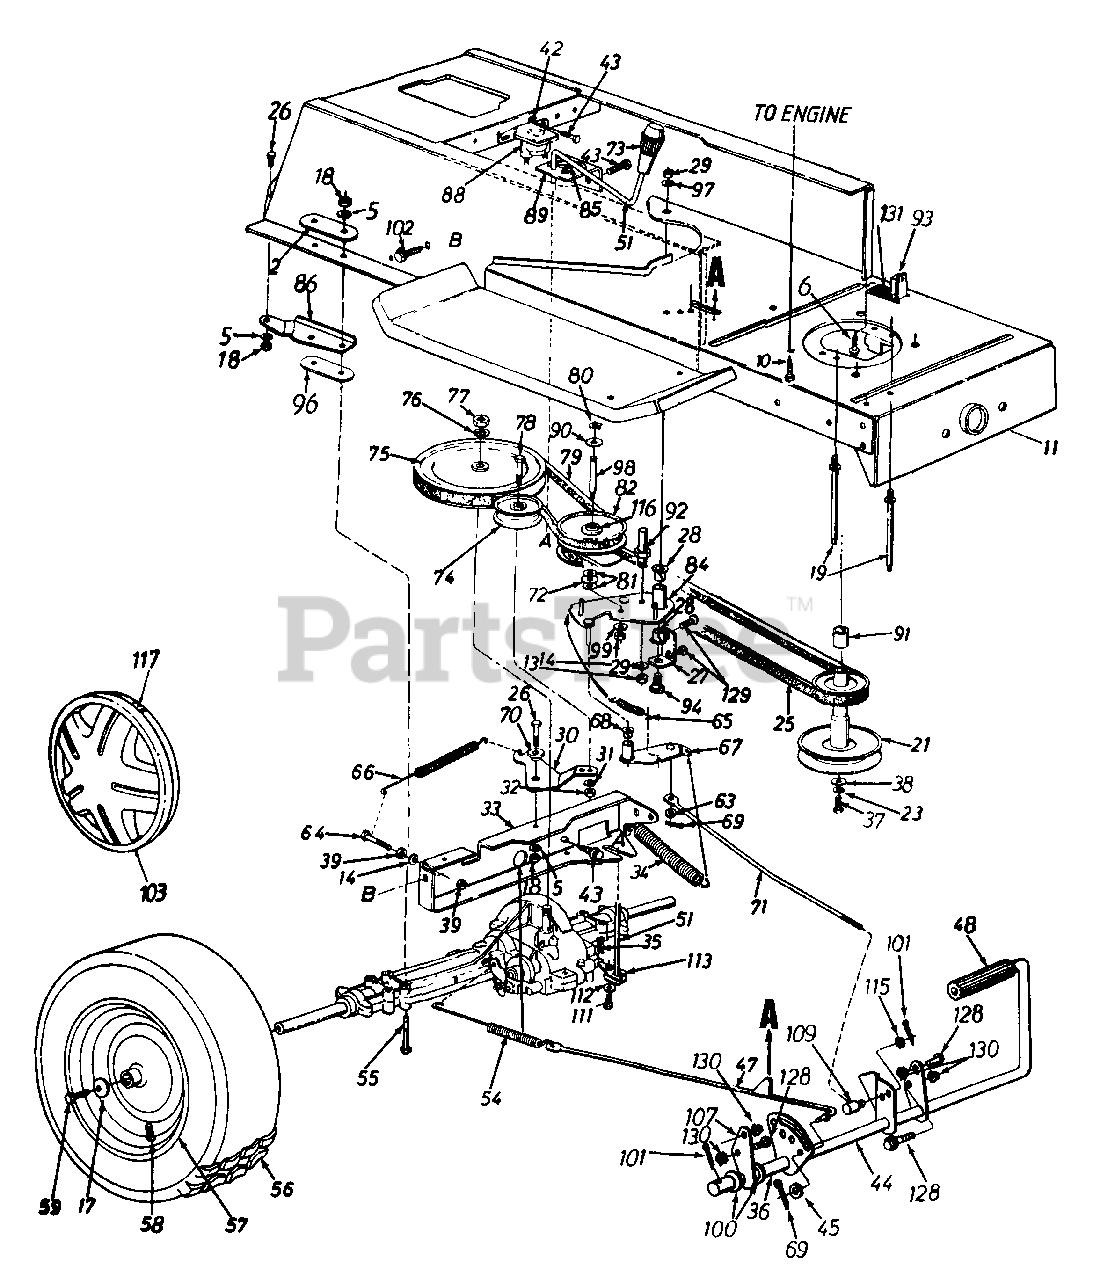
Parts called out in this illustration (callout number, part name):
5	L-Wash. 5/16" I.D.
6	Self-tap screw 1/4 x .50
10	Hex TT-Tap Scr. 3/8-16 x 1.5" Lg.
13	Hex Nut 1/4-20 Thd. (Gr. 5)
14	L-Wash. 1/4" I.D.
17	Bell-Wash. .345" I.D. x .88"
18	Hex Nut 5/16-18 Thd. (Gr. 5)
19	Belt Guard Stud 4.75" Lg.
21	Engine Pulley
23	L-Wash. 7/16" I.D.
25	Variable-Speed Belt
26	Hex Bolt 5/16-18 x .75" Lg.
27	Bearing Shaft Bracket Ass'y.
28	Flanged Nyliner Brg. 5/8" I.D. x .88" Lg.
29	Hex Nut 3/8-24 Thd.
31	L-Wash. 3/8" I.D.
32	Hex Nut 3/8-24 Thd.
35	Inter. Cotter Pin
36	Spacer .63" I.D.
37	Cap Scrw 7/16-20 x 1.25
38	Flat Washer .450
39	Hex Nut 1/4-28 Thd.
42	Ext. L-Wash. 1/4" I.D.
43	Hex Wash. Hd. S-Tap Scr. 1/4-20 x .50" Lg.
47	Brake Rod Ass'y.
48	Foot Pad
51	Shift Lever Ass'y.
54	Ext. Spring .59" O.D. x 7.08"
55	Hex Bolt 5/16-18 x 3.5" Lg.
56	Wheel Ass'y. Comp.
57	Wheel Rim Only
58	Air Valve (Service Only)
59	Hex Bolt 5/16-24 x .75" Lg.
63	Fl-Wash. .34" I.D. x .68" O.D.
64	Hex Bolt 1/4-28 x 1.25" Lg.
65	Ext. Spring
66	Ext. Spring .62" O.D. x 6.12"
68	Flanged Bearing
69	Cotter Pin 3/32" Dia.
70	Shoulder Spacer .27" Lg
71	Speed Control Link
72	Truss Bearing .56 Dia. x 1.25"
73	Shift Knob
74	Fl-Idler Pulley 3.12" Dia
75	"V" Pulley
76	Bell-Wash .56" I.D. x 1.125"
77	Hex Jam Nut 5/16-18 Thd.
78	Hex Bolt 3/8-24 x 1 75" Lg.
79	Variable Speed Belt
80	Snap Ring .56" Dia
81	Fl-Wash.
82	Variable Speed Pulley Ass'y. 5" O.D.
90	Teflon Washer .565" I.D.
91	Spacer 1" I.D. x 1.25" Lg
92	Belt Keeper 3" Lg.
93	Safety Switch (Clutch)
94	Shld. Bolt 3/8-24 x 3.12" Lg.
96	Transaxle Spacer
97	Bell-Wash .38" I.D. x .88"
98	Shaft .56" Dia. x 3.875" Lg.
99	Bell-Wash. 39" I.D. x 1.12"
100	Fl-Wash. .64" I.D. x .94"
101	Cotter Pin 1/8" Dia x 1.25"
102	Hex Wash Hd. Scr. 5/16-18 x .62" Lg.
103	Hub Cap (Gray)
111	Hex Bolt 1/4-28 x .50" Lg.
112	Bell-Wash. .265" I.D. x .75"
113	Shift Lever Link Ass'y.
115	Fl-Wash. .385" I.D. x .62"
116	Needle Brgs.
117	Spring Clip
128	Hex Wash TT-Tap Scr. 5/16-18 x .75" Lg
129	Hex Wash AB-Tap Scr. 5/16-18 x .75" Lg.
130	Hex Sems Nut 5/16-18 Thd.
131	Spring Switch
